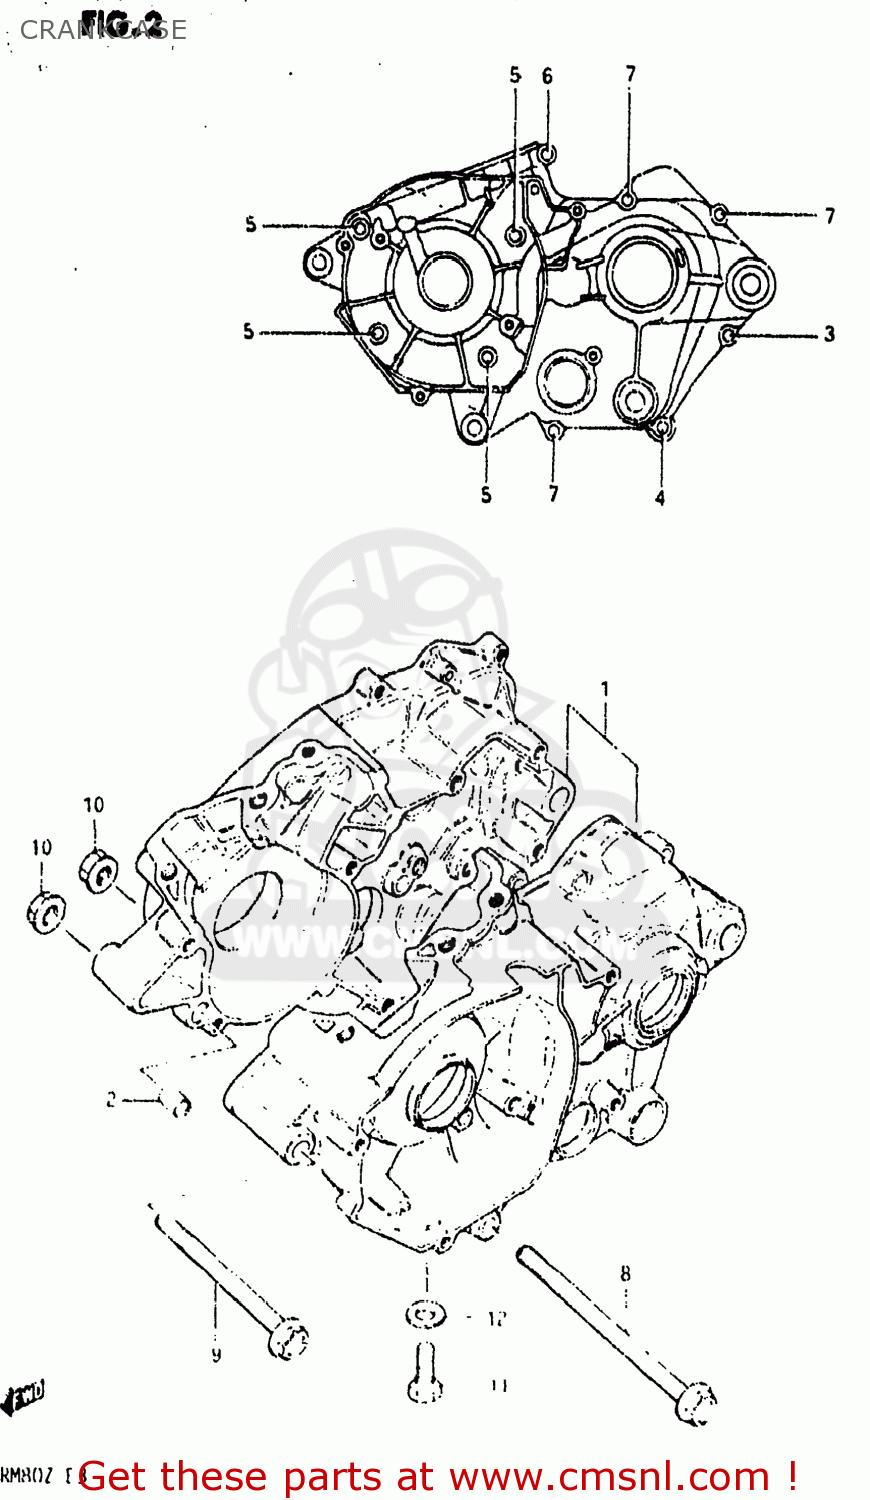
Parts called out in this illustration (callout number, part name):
1	CRANKCASE ASSEMBLY
2	PIN
3	SCREW
4	SCREW (6X45)
5	SCREW
6	SCREW (6X35)
7	SCREW
8	BOLT
9	BOLT(8X95)
10	NUT
11	BOLT
12	GASKET 8.2X14X1 (NAS)
